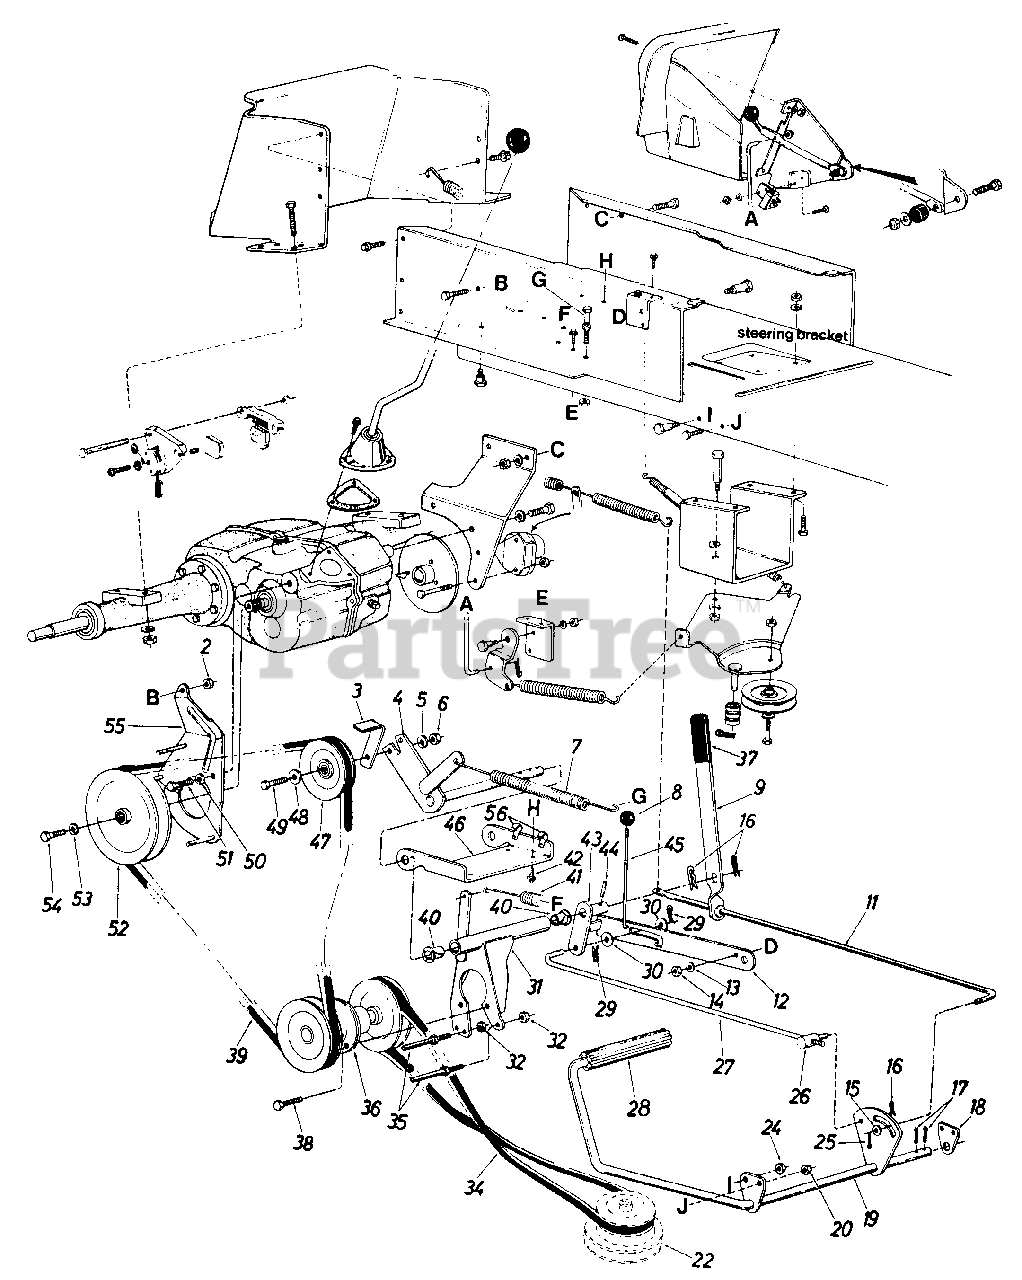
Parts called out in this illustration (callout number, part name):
2	Hex L-Nut 3/8-16 Thd.
5	L-Wash. 3/8" Scr.
6	Hex Nut 3/8-16 Thd.
7	Ext. Spring (Drive Idler)
8	Knob (Parking Brake)
9	Hand Brake Lever
9	Hairpin Cotter 3/8" Rod
11	Brake Rod
12	Parking Brake Cam
13	Fl-Wash. 5/16" Scr.
14	Hex Nut 5/16-18 Thd.
15	Fl-Wash. 5/16" Scr.
16	Hairpin Cotter 3/8" Rod
17	Cotter Pin 1/8" Dia. x 1.00" Lg.
18	Clutch Rod Brg. Brkt.
19	Clutch Brake Pedal Ass'y.
20	Hex Cent. L-Nut 3/8-16 Thd.
22	Engine Pulley 4.75 & 5.56
24	Hex Cent. L-Nut 3/8-16 Thd.
25	Cotter Pin 3/32" Dia. x .75" Lg.
26	Pivot Bushing
27	Brake Cam Rod
28	Foot Pad
29	Hairpin Cotter 3/8" Rod
30	Fl-Wash. 3/8" I.D. x 1.00" O D. x .030
31	Jack Shaft Mtg. Brkt. Ass'y.
32	Hex Top L-Nut 3/8-16 Thd.
34	VBelt 1/2 x 59" Lg. (Polyester)
35	Stud 3/8-16 x 3.62" Lg. Special
36	Jack Shaft Ass'y.
37	Flat Grip
38	Hex Sem Scr. 5/16-18 x .75" Lg.
39	VBelt 1/2 x 40" Lg. (Kevlar)
40	Nyliner 5/8" I.D. x .88" Lg.
41	Ext. Spring (Jack Shaft)
42	Hex Thd. Rolling Scr. 1/4-20 x .50" Lg.
43	Clutch-ldler Horn Ass'y.
44	Spring Pin Spiral 1/4" Dia. x 1.00" Lg.
45	Parking Brake Link
46	Idler Mtg. Brkt. Drive
47	4" "V"-Idler Pulley
48	Fl-Wash. 3/8" I.D.
49	Hex Scr. 3/8-16 x 1.75" Lg.
50	L-Wash. 3/8" Scr.
51	Hex Scr. 3/8-16 x .75" Lg.
52	VPulley 7.0" O.D. (Transaxle)
53	L-Wash. 3/8" I.D.
54	Hex Scr. 3/8-24 x .75" Lg.
55	Belt Guard Ass'y.
56	Plastic Hose Clamp
